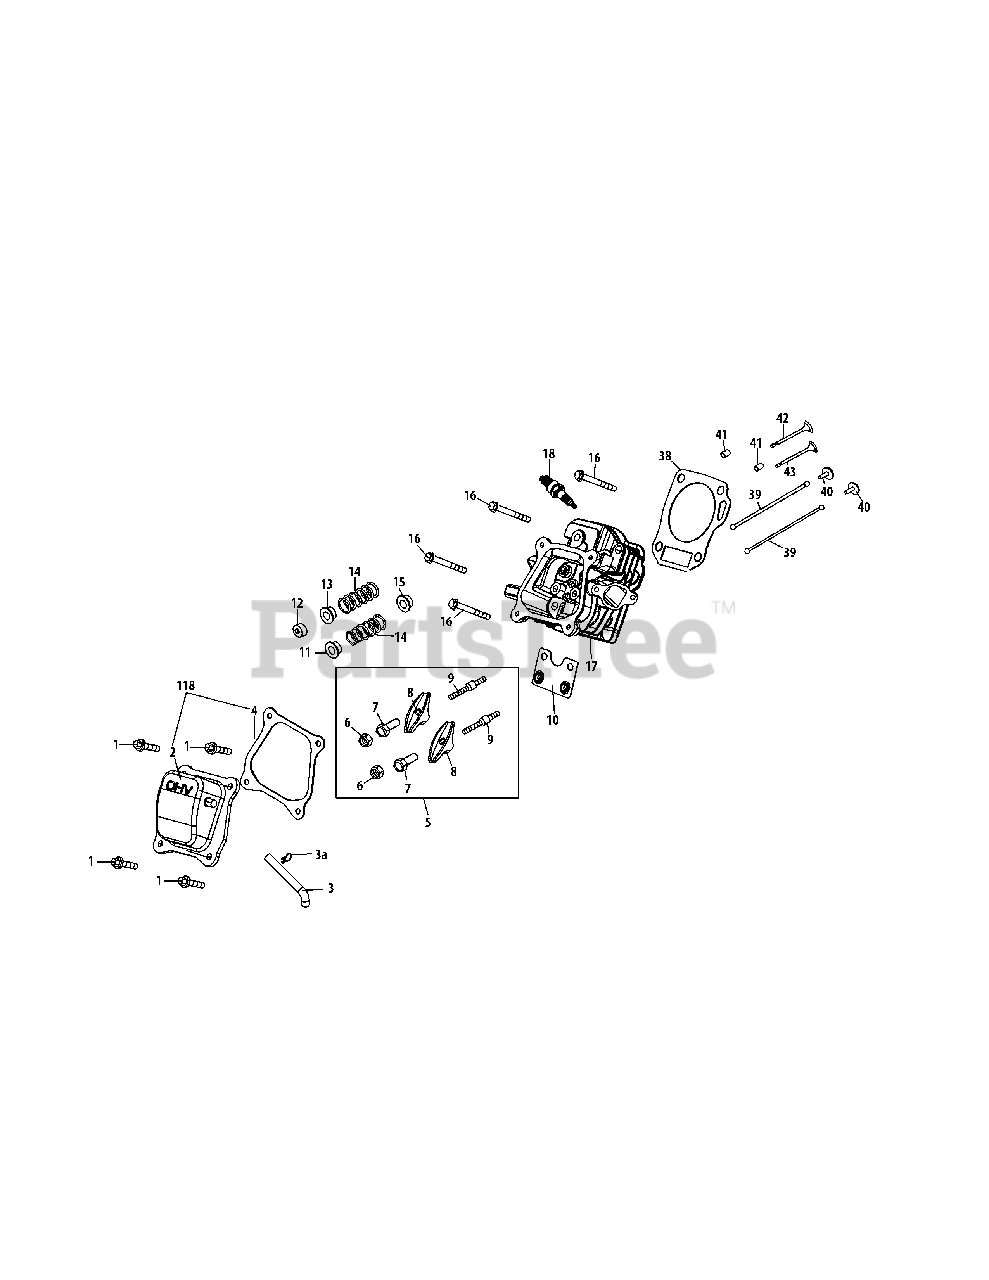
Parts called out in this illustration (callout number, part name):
1	Bolt M6×16
2	Valve Cover
3	Breather Hose
4	Valve Cover Gasket
5	Rocker Arm Assembly
6	Nut,Pivot Locking
7	Adjusting Nut, Valve
8	Rocker Arm
9	Bolt, Pivot
10	Push Rod Guide
11	Retainer, Intake Valve Spring
12	Adjuster, Exhaust Valve
13	Retainer, Exaust Valve Spring
14	Valve Spring
15	Intake Valve Seal
16	Bolt M8×55
17	Cylinder Head Assembly
18	Spark Plug
38	Gasket, Cylinder Head
39	Push Rod Kit
41	Dowel Pin 10×16
118	Valve Cover Kit
